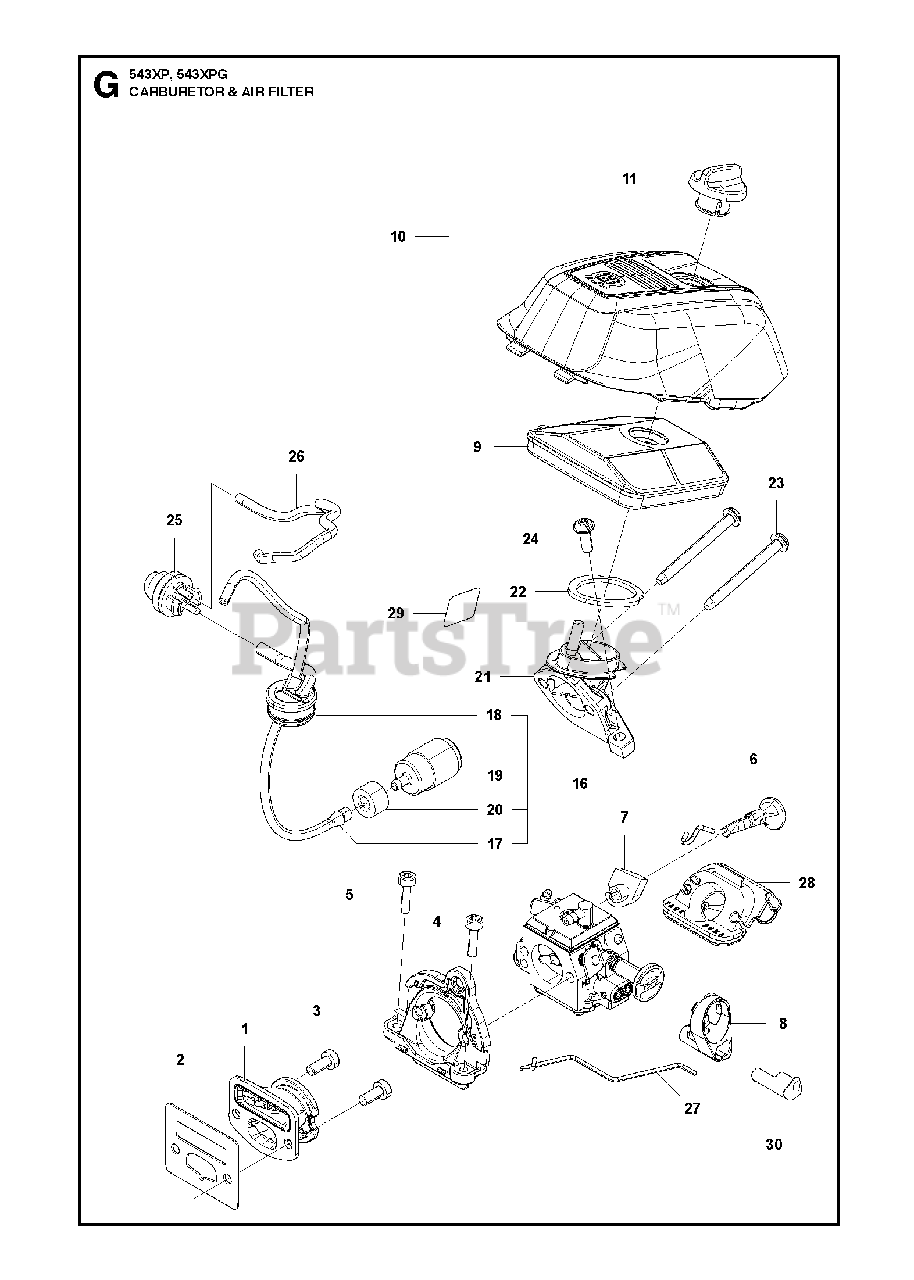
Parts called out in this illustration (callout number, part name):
1	INLET PIPE ASSY
3	BOLT
4	FLANGE ASSY
5	BOLT
6	ROD CHOKE XC25
8	GROMMET ID
10	AIR FILTER COVER
11	KNOB XC25
17	FUEL HOSE L215
18	GROMMET
20	COLLAR
22	SEAL MANIFOLD
24	SCREW M5 X 14
25	PRIMARY BTN
26	FUEL HOSE L170
27	THROTTLE ROD
